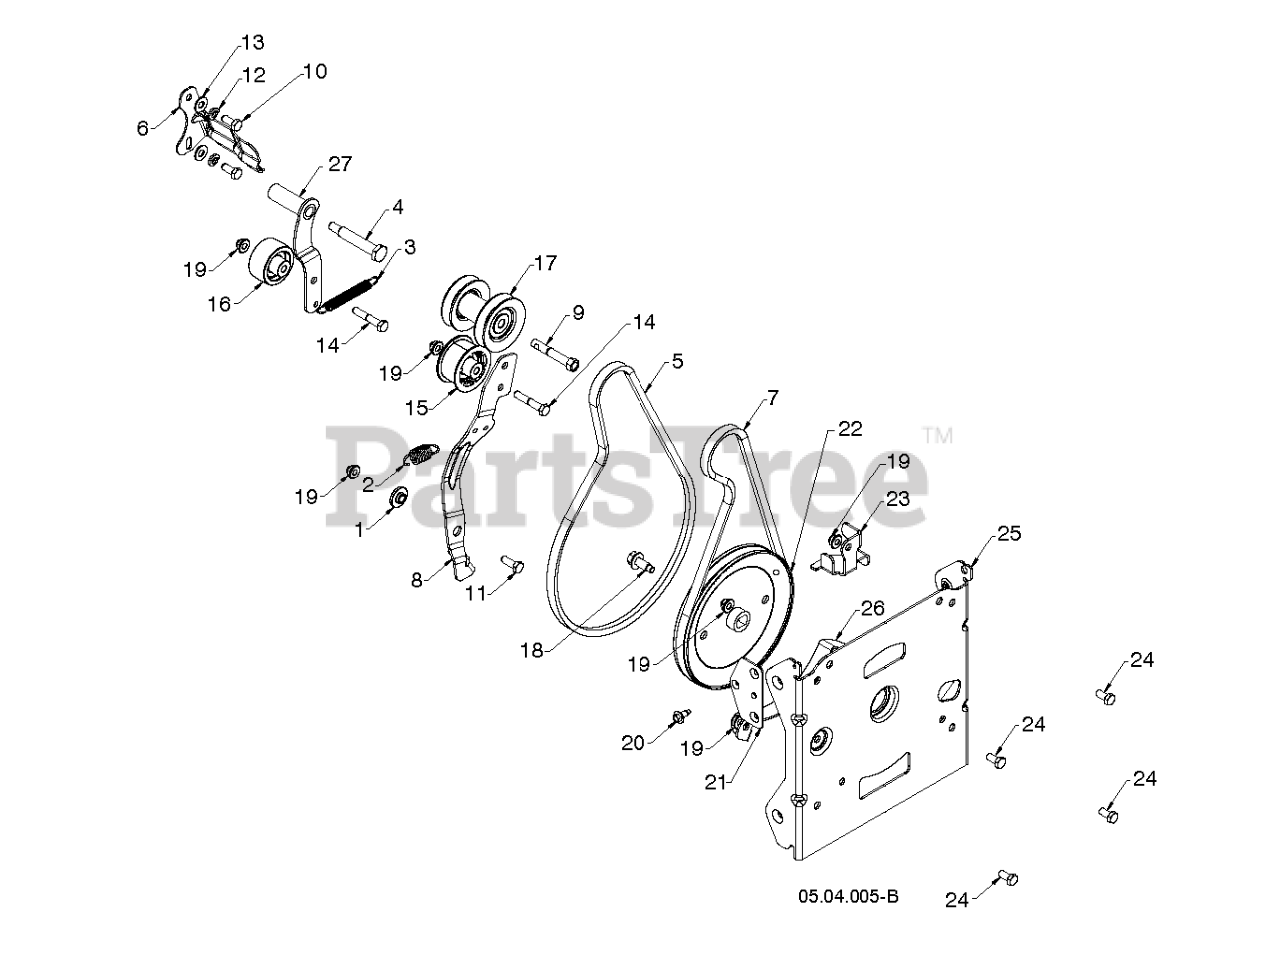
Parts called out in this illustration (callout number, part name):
1	BUSHING.BRAKE.ARM
2	SPRING RETURN, IDLER ARM, IMPE
3	SPRING RETURN IDLER ARM
4	BOLT 5/16-24X2.25 HEX HEAD SHO
5	BELT.DRIVE.SNOW.DUAL
6	BELT KEEPER BRACKET
7	LOW CRANK IMPELLER BELT
8	ARM.IDLER.AUTO-PH.676
9	BOLT.ENGINE.PULLEY
10	BOLT 5/16-24X2.25 HEX HEAD SHO
11	BOLT HEXAGON BOLT 5/16-18 X 7/
12	WASHER SPRING LOCK WASHER WITH
13	WASHER 11/32 X 11/16 X 14 GA T
14	BOLT, HEX 5/16-18X1-3/4
15	PULLEY.IDLER.FLNGLESS.W/SPACER
16	PULLEY.IDLER.FLNGLESS.W/SPACER
17	PULLEY.ASM.IMPELLER/DRIVE
18	SCREW HEXAGON HEAD FLANGE 3/8-
19	NUT HEXAGON FLANGE 5/16-18 ST
20	HEX.WASHER.HEAD 1/4-20 X .65
21	BRACKET NUT BLACK ZINC PLATE
22	PULLEY IMPELLER DD 4L
23	GUIDE.LOWER.AUGER.BELT.479
25	BRACKET.AUG.HOUSING.INTER.BLAC
26	BRACKET.BELT.KEEPER.LOWER.BLAC
27	ARM IDLER DRIVE WELDMENT_HOT
